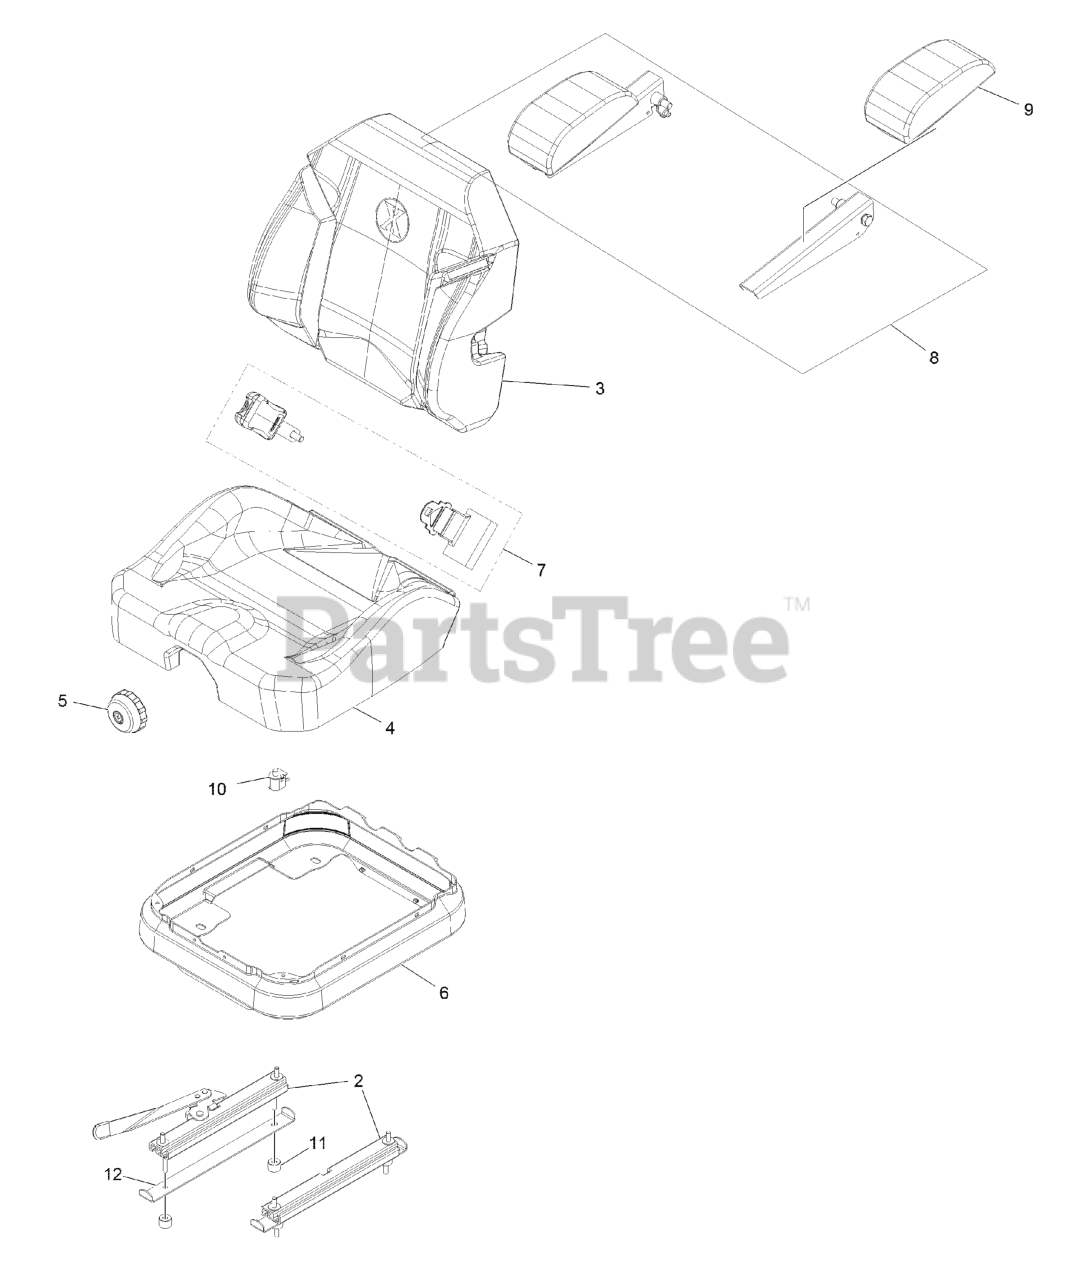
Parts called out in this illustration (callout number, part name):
2	COVER-SEAT BACK
3	COVER-SEAT CUSHION
4	ARMREST KIT
4:1	CUSHION-REST, ARM
5	KIT-SEAT BELT SERVICE
6	TRACK-SEAT
8	SWITCH-BAIL
10	WASHER-FLAT
